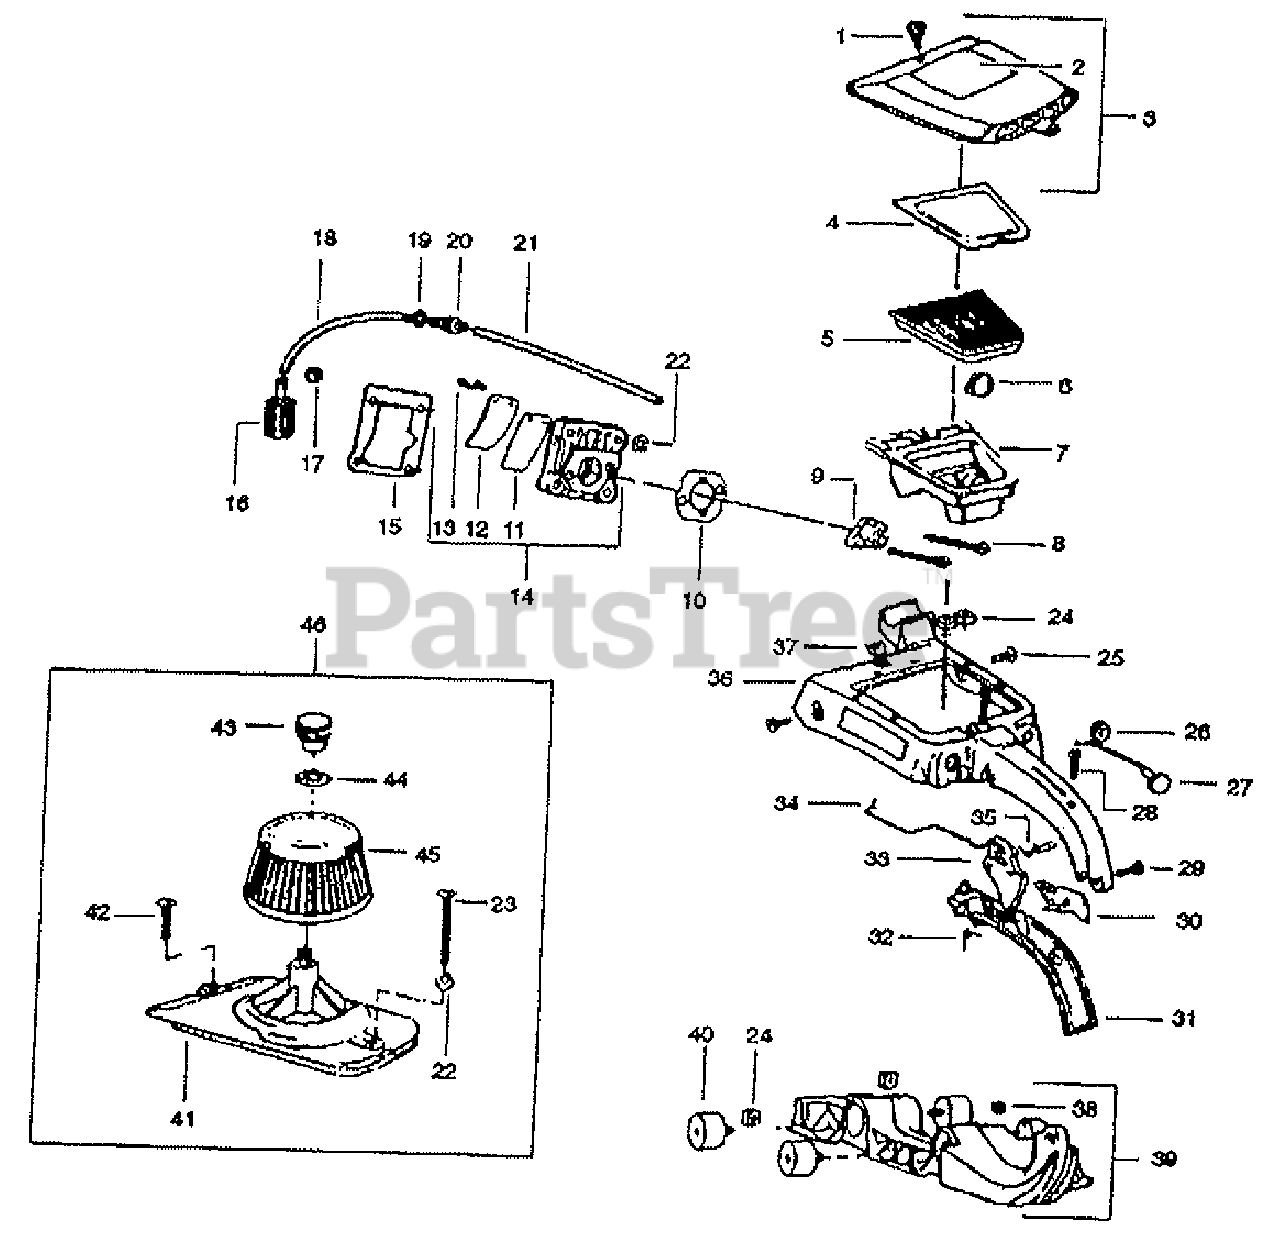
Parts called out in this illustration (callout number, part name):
1	Top Cover Knob
2	Top Cover Decal
3	Top Cover Ass'y Complete
4	Air Filter (R)
5	Air Filter (L)
7	Air Box Boot
9	Blow Back Tube
11	Reed Valve
12	Reed Back Plate
13	Reed Screw
14	Reed Valve Ass'y
16	Fuel Filter Ass'y
17	Speed Clip
18	Fule Hose
20	Connector
21	Fuel Hose
27	Choke Knob & Wire Ass'y
30	Throttle Lockout
31	Lower Grip Ass'y
32	Spring
33	Throttle Trigger
34	Throttle Link
35	Throttle Pin
36	Top Frame
39	Bottom Frame & Nut Ass'y
40	Shcok Absorber
41	Fillter Base Ass'y
45	Filter Element
46	Air Filter Kit
